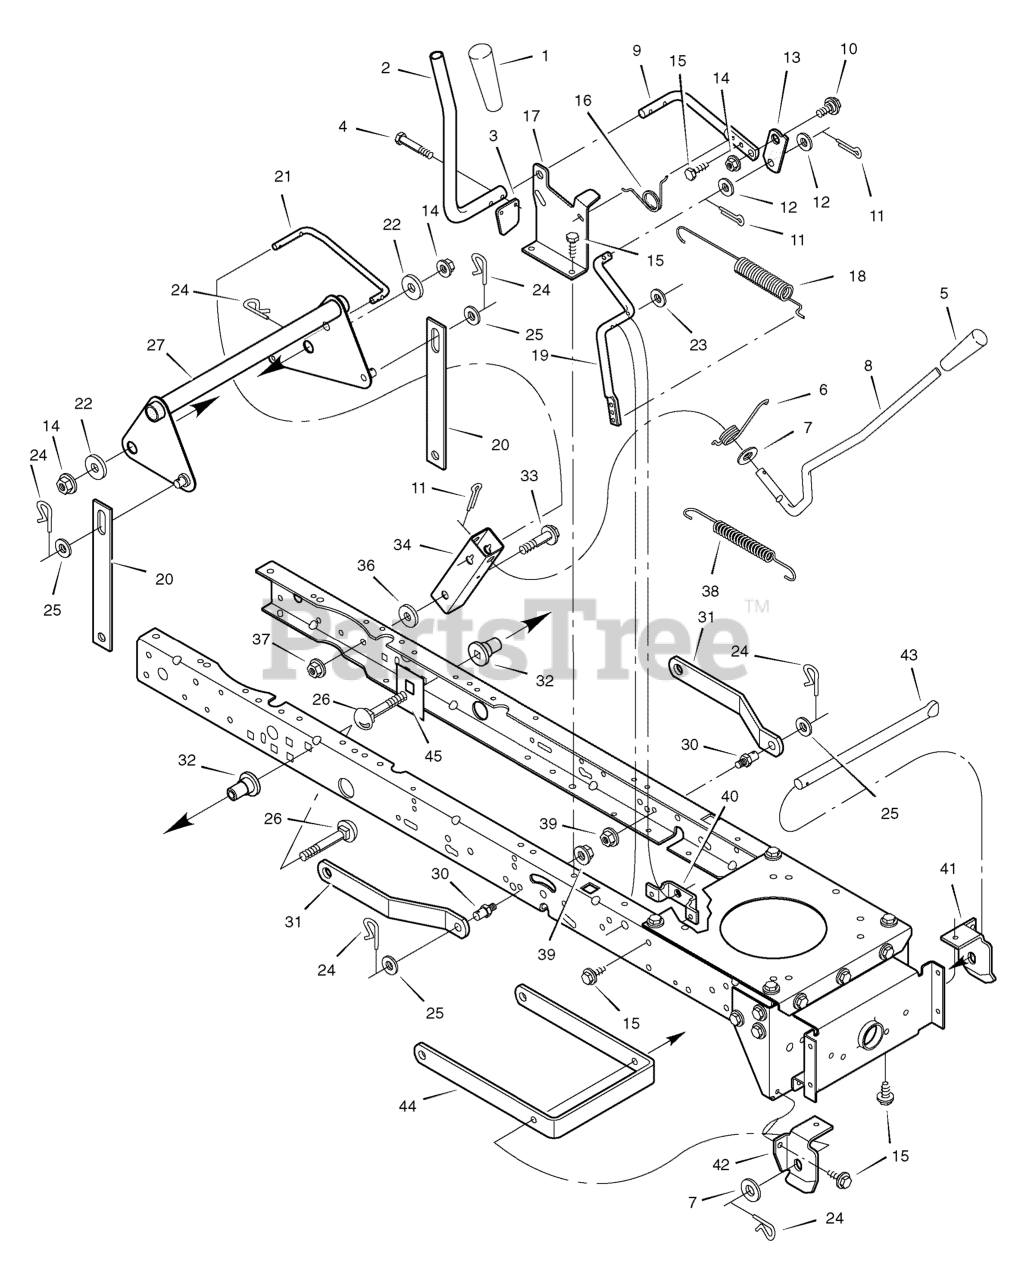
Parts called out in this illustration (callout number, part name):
1	GRIP
2	HANDLE, PTO
3	PAD, Switch
4	Screw, Hex
5	GRIP
8	HANDLE, Lift
9	LEVER, PTO
10	BOLT, Shoulder
11	PIN, Cotter
13	LINK, PTO
14	NUT, Flange
17	BRACKET, PTO
18	SPRING, PTO
19	CRANK, PTO
20	LINK, Lift
21	LINK, Lift Handle
24	PIN, Hair
26	BOLT, Carriage
27	LEVER ASSEMBLY, Lift
30	PIN
31	BRACKET, Rear Suspension
32	SPACER, Lifter
33	BOLT, Shoulder
34	BRACKET, Pivot
37	NUT, Flange
39	NUT, Flange
40	BRACKET, PTO
41	HANGER, Left Deck
42	HANGER, Right Deck
43	ROD, Hanger
44	BRACKET, Suspension
45	PLATE, Stiffening
